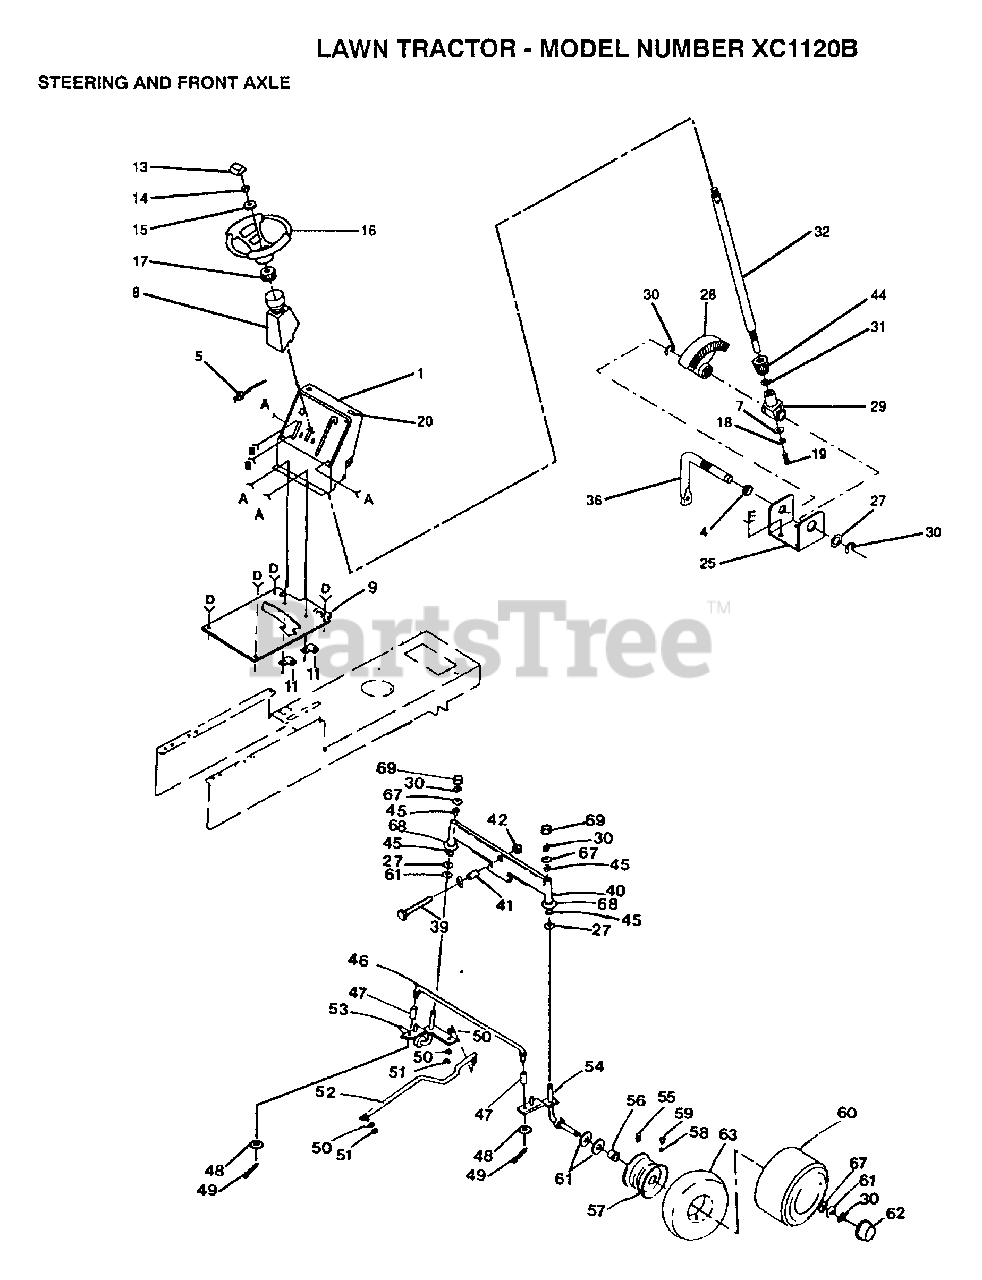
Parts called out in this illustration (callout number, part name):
4	NYLINER T
8	"TUBE, STR SHAFT"
11	CLIP T
13	INSERT-WHEEL LT
15	WASHER
17	ADAPTER LT
18	LOCKWASHER
19	"SCREW,SPECIAL"
25	"BRKT,STEERING"
27	WASHER .T
29	SUPPORT.SHAFT
30	RING
31	THRUST WASHER
39	BOLT LT
41	BEARING
42	"NUT-LOC,FLANGE LT"
44	"GEAR,PINION"
45	COL. SRTG. BEAR.
48	WASHER
49	COTTER PIN
50	LOCKWASHER
53	SPINDLE-LH LT
55	FITTING LT
56	"FLANGE, BEARING"
58	VALVE CAP
59	VALVE STEM LT
61	WASHER
62	HUB CAP
63	TUBE.5.3/4.5/6
67	WASHER
68	WASHER
69	CAP
